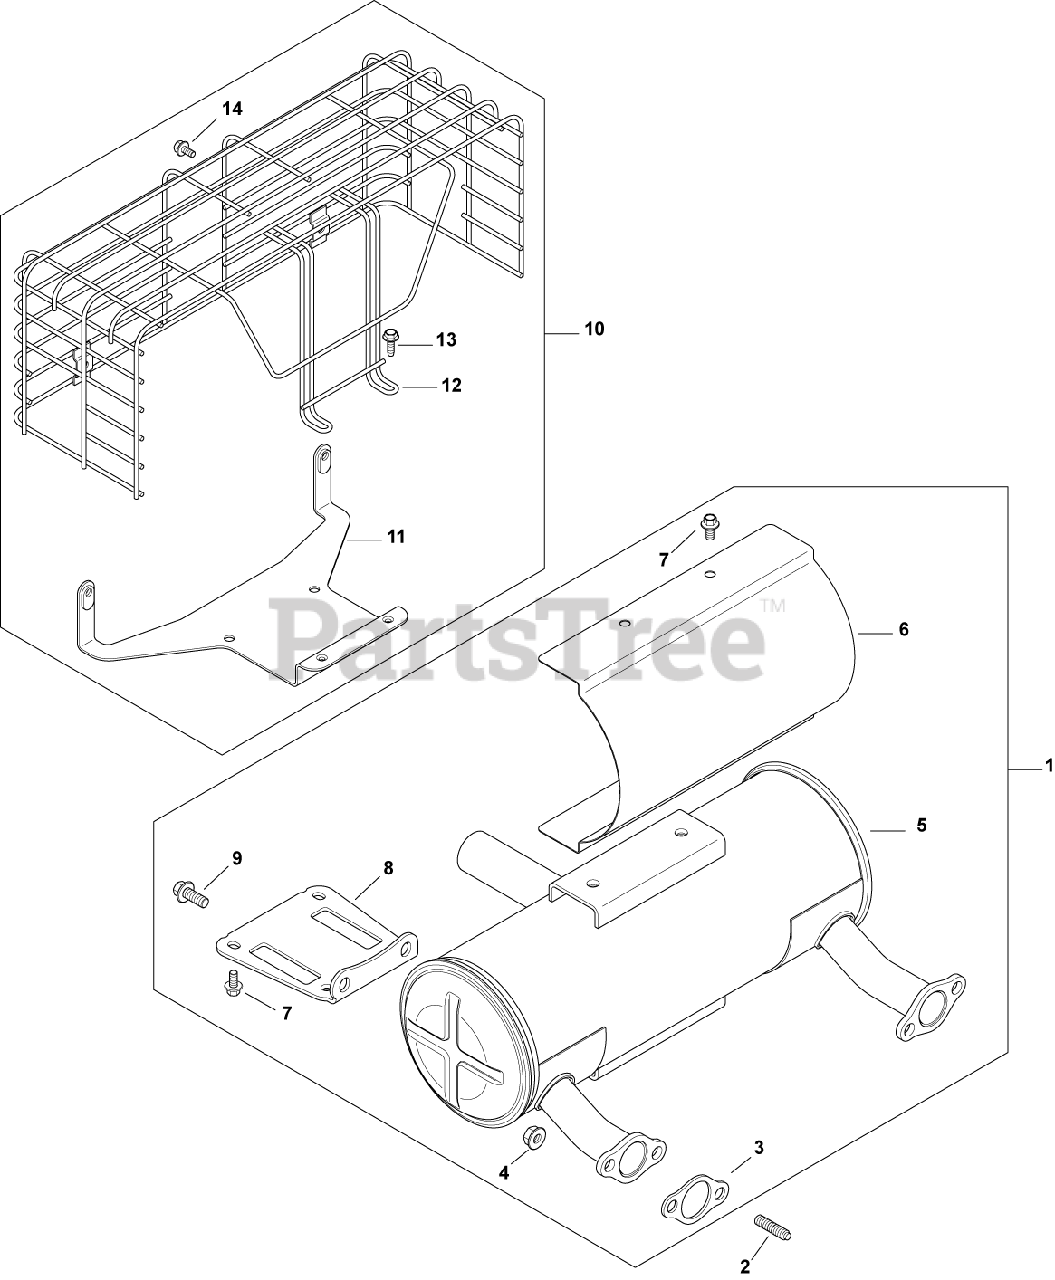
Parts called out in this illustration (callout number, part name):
1	MUFFLER KIT, CENTER/STRAIGHT
2	STUD, EXHAUST-USE 25 072 24-S
3	GASKET, EXHAUST
4	NUT, FLG M8X1.25
5	MUFFLER, CENTER/STRAIGHT USE 24 068 131-S
6	SHIELD, HEAT-USE 24 314 50-S
7	SCREW, FLG M6X1.0X12
8	BRACKET, MUFFLER
9	SCREW, FLG M8X1.25X20
10	KIT, MUFFLER GUARD
11	BRACKET, EXHAUST GUARD
12	GUARD, MUFFLER
13	SCREW,FLG THD FRM M5X0.8X16-(#25086398S)
14	SCREW, HVY FLG M5X.8X10
